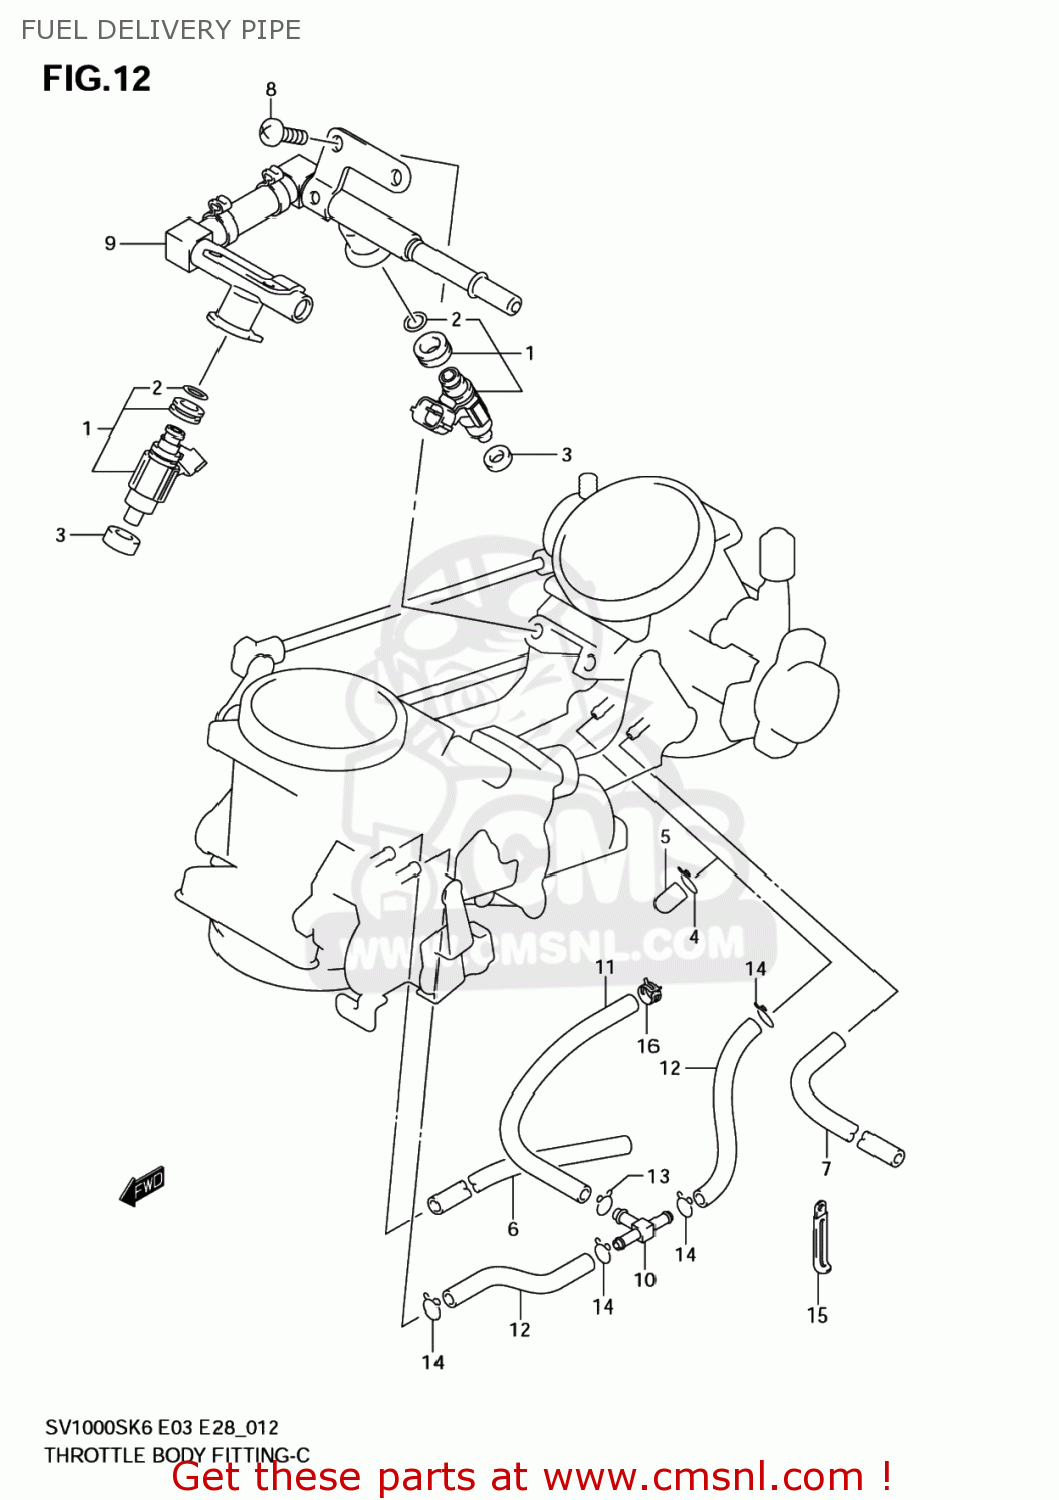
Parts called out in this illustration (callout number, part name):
1	INJECTOR ASSY
2	O RING
3	CUSHION,FUEL INJECTOR
4	CLIP
5	CAP
6	HOSE(3.2X7.4X225)
7	HOSE
8	SCREW
9	DELIVERY PIPE ASSY
10	NIPPLE
11	HOSE
12	HOSE(3.2X7.4X225)
13	CLIP
14	CLIP
15	CLAMP(L:45)
16	CLIP
